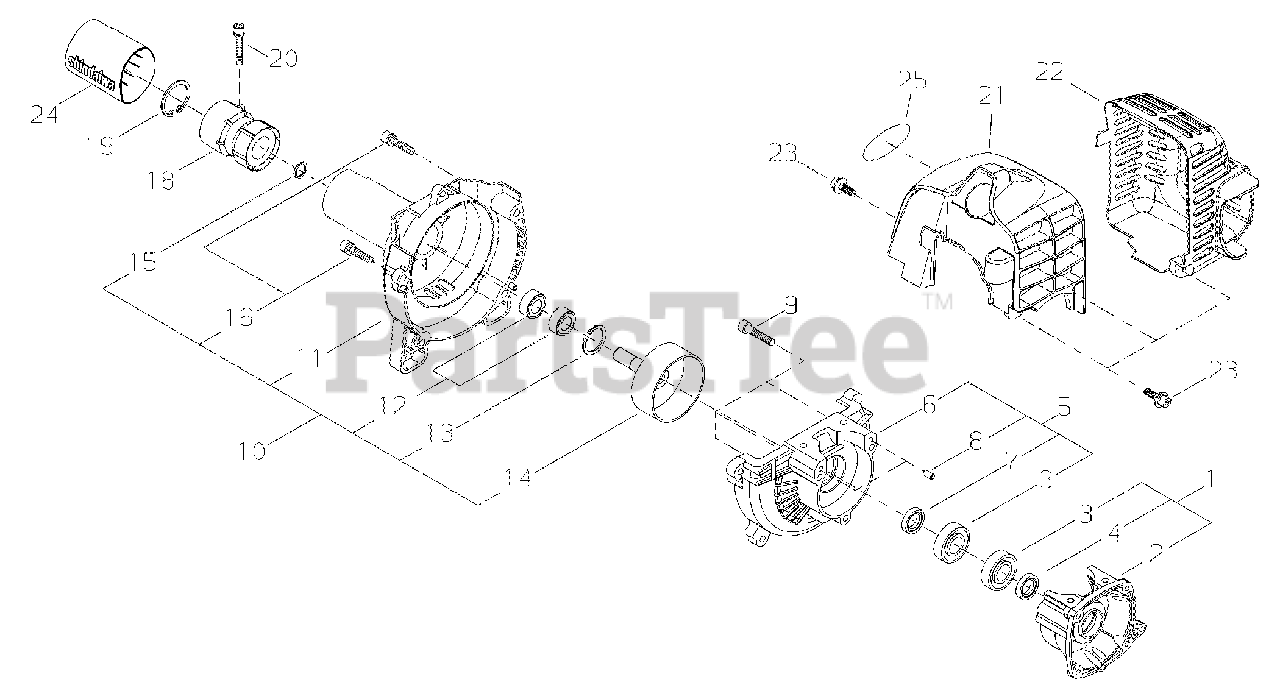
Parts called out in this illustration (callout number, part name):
1	CRANKCASE ASSY - REAR
2	CRANKCASE - REAR
3	BEARING, BALL - 6001C3
4	SEAL, OIL - 12
5	CRANKCASE ASSY - FRONT
6	CRANKCASE - FRONT
7	SEAL, OIL - 12
8	PIN - LOCATING
9	SCREW - 5X25
10	FAN CASE ASSY
11	CASE, FAN
12	BEARING, BALL - 6000
13	RING, RETAINING - 26
14	DRUM, CLUTCH
15	RING, RETAINING
16	SCREW - 5X16
18	CUSHION
19	RING, RETAINING - 40
20	SCREW - 5X22
21	COVER, ENGINE
22	COVER, EXHAUST
23	SCREW - 4X16
24	PROTECTOR
25	LABEL - MODEL 242
